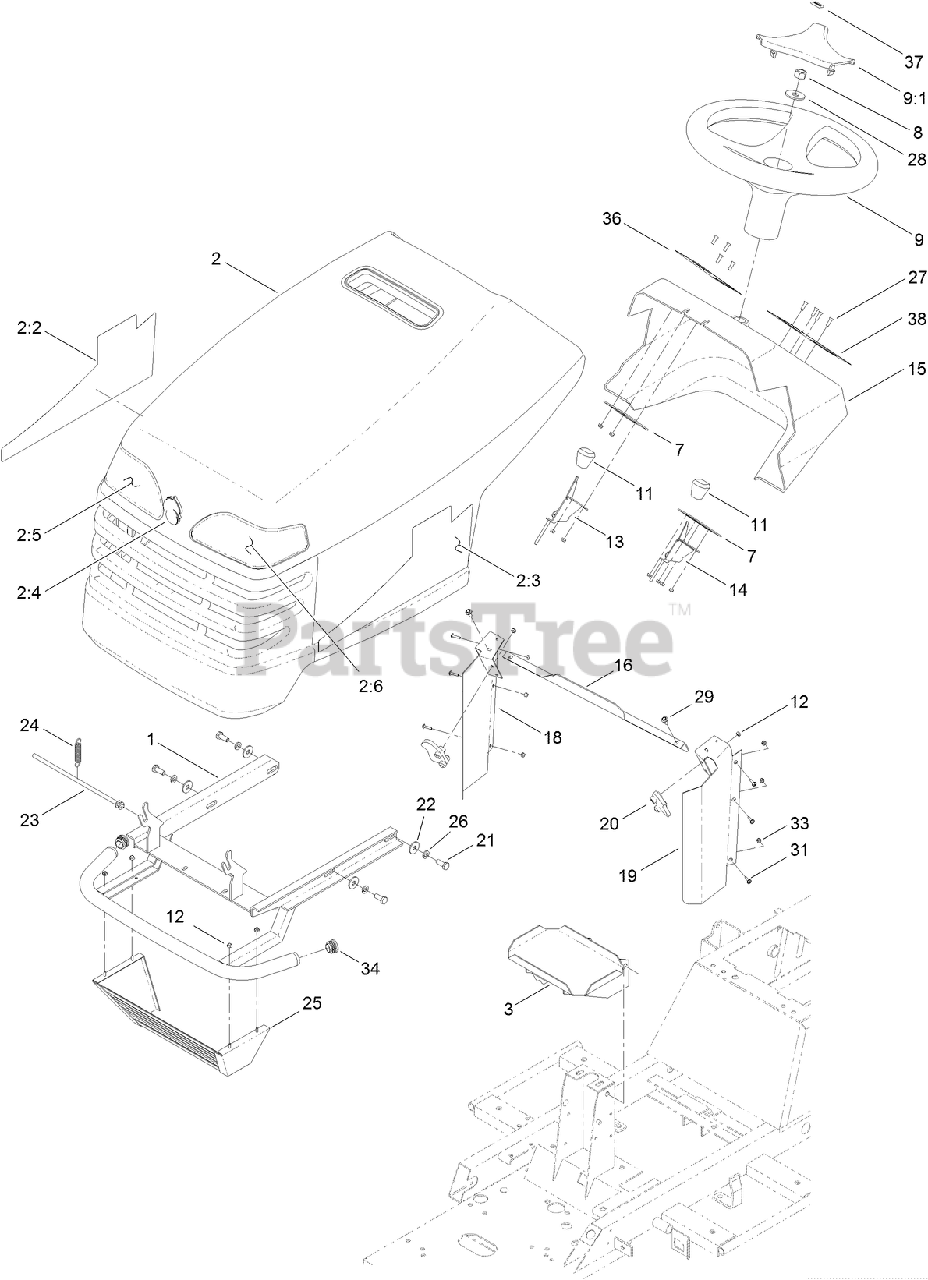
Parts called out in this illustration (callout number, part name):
1	SUPPORT-BUMPER
2	HOOD ASM
2:2	DECAL-HOOD, RH
2:3	DECAL-HOOD, LH
2:4	EMBLEM
2:5	LENS-HEADLAMP, RH
2:6	LENS-HEADLAMP, LH
3	TRAY-BATTERY
8	NUT-HEX
9	WHEEL-STEERING
9:1	COVER-WHEEL, STEERING
12	NUT-LOCK
13	CONTROL-THROTTLE (TWIN)
14	CONTROL-CHOKE (TWIN)
15	PANEL-DASH
18	PANEL-RIGHT
19	PANEL-LEFT
20	LATCH-HOOD
21	SCREW-HH
22	WASHER-PLAIN
24	SPRING-HOOD
25	GUARD-MUFFLER
26	WASHER-LOCK
28	Washer
33	NUT-HEX
34	PLUG-END, TUBE
37	DECAL
38	DECAL-CHOKE/PTO
